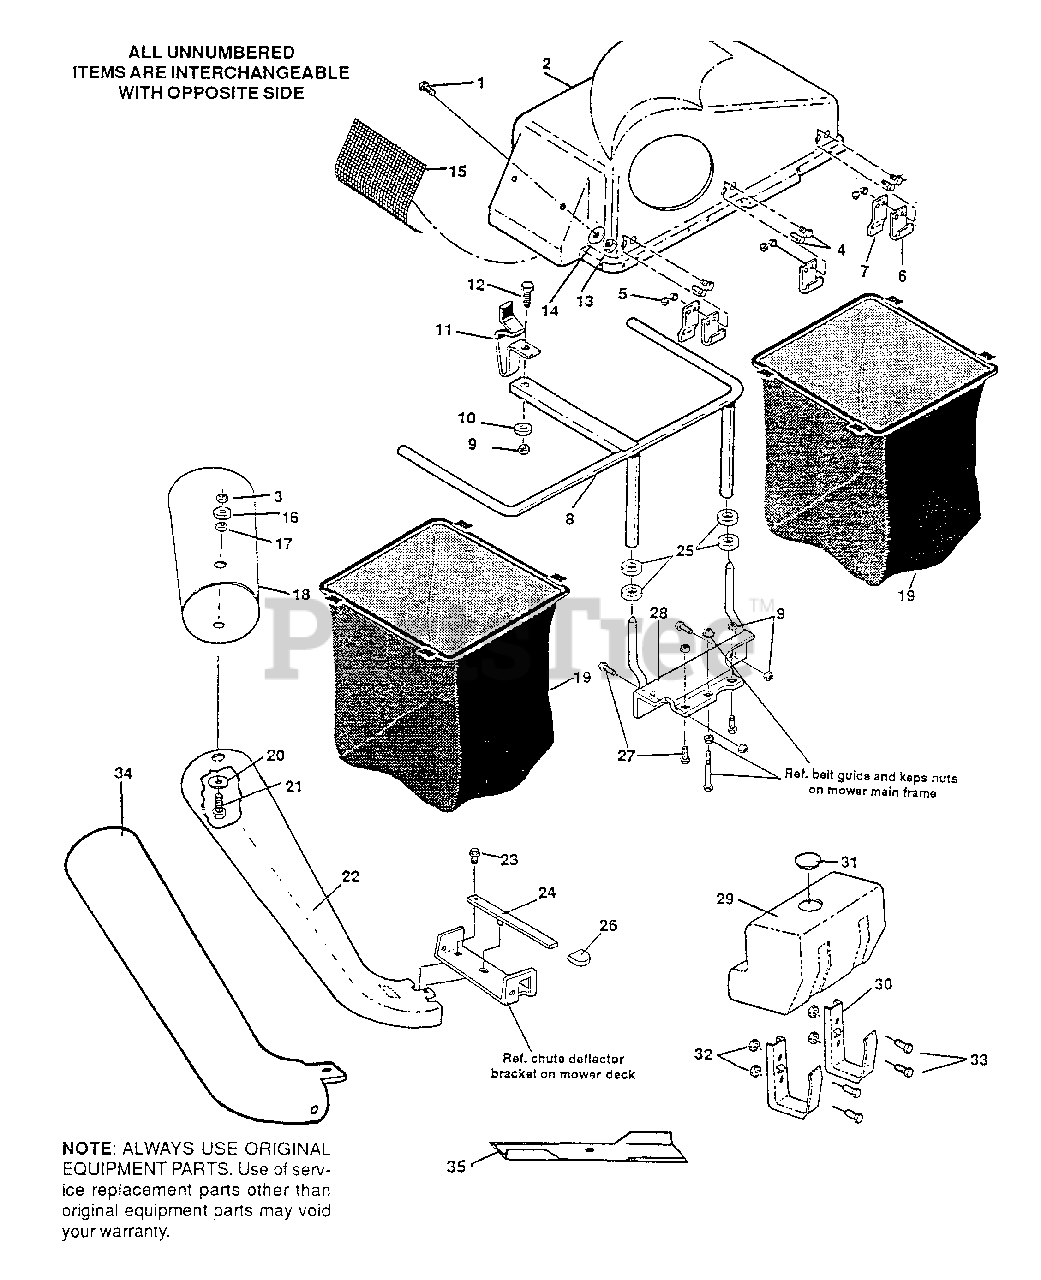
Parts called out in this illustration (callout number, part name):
1	Screw, Sl Fl Hd, No. 10-24 x 5/8 In.
3	Locknut, 1/4-20 Thd.
4	Screw, Sl Rd Hd, 1/4-20 x 5/8 In.
5	Nut, Keps, 1/4-20 Thd.
6	Hinge, Cover
7	Strap, Retainer
8	Support Assembly
9	Locknut, 5/16-18 Thd.
10	Flatwasher, 11/32 In.
11	Latch, Bagger
12	Screw, Hex Hd, 5/16-18 x 1 /2 In.
13	Nut, Keps, No. 10-24 Thd.
14	Flatwasher, 13/64 In.
16	Flatwasher, 9/32 In.
17	Rubber Grommet
18	Upper Tube Assembly
20	Flatwasher, 5/16 In.
21	Screw, Hex Hd, 1/4-20 x 3/4 In.
22	Chute, Transition
23	Screw, Taptite, 5/16-18 x 1/2 In.
24	Lever, Latch
25	Spacer
27	Screw, Hex Hd, 5/16-18 x 5/8 In.
28	Lower Support
29	Tank, Weight
30	Bracket, Weight
31	Plug, Weight Tank
32	Nut, Hex Hd Wide Flange, 5/16-18 Thd.
33	Screw, Hex Hd, 5/16-18 x 1 In.
34	Chute, Transition
35	Blade, Hi-Lift
